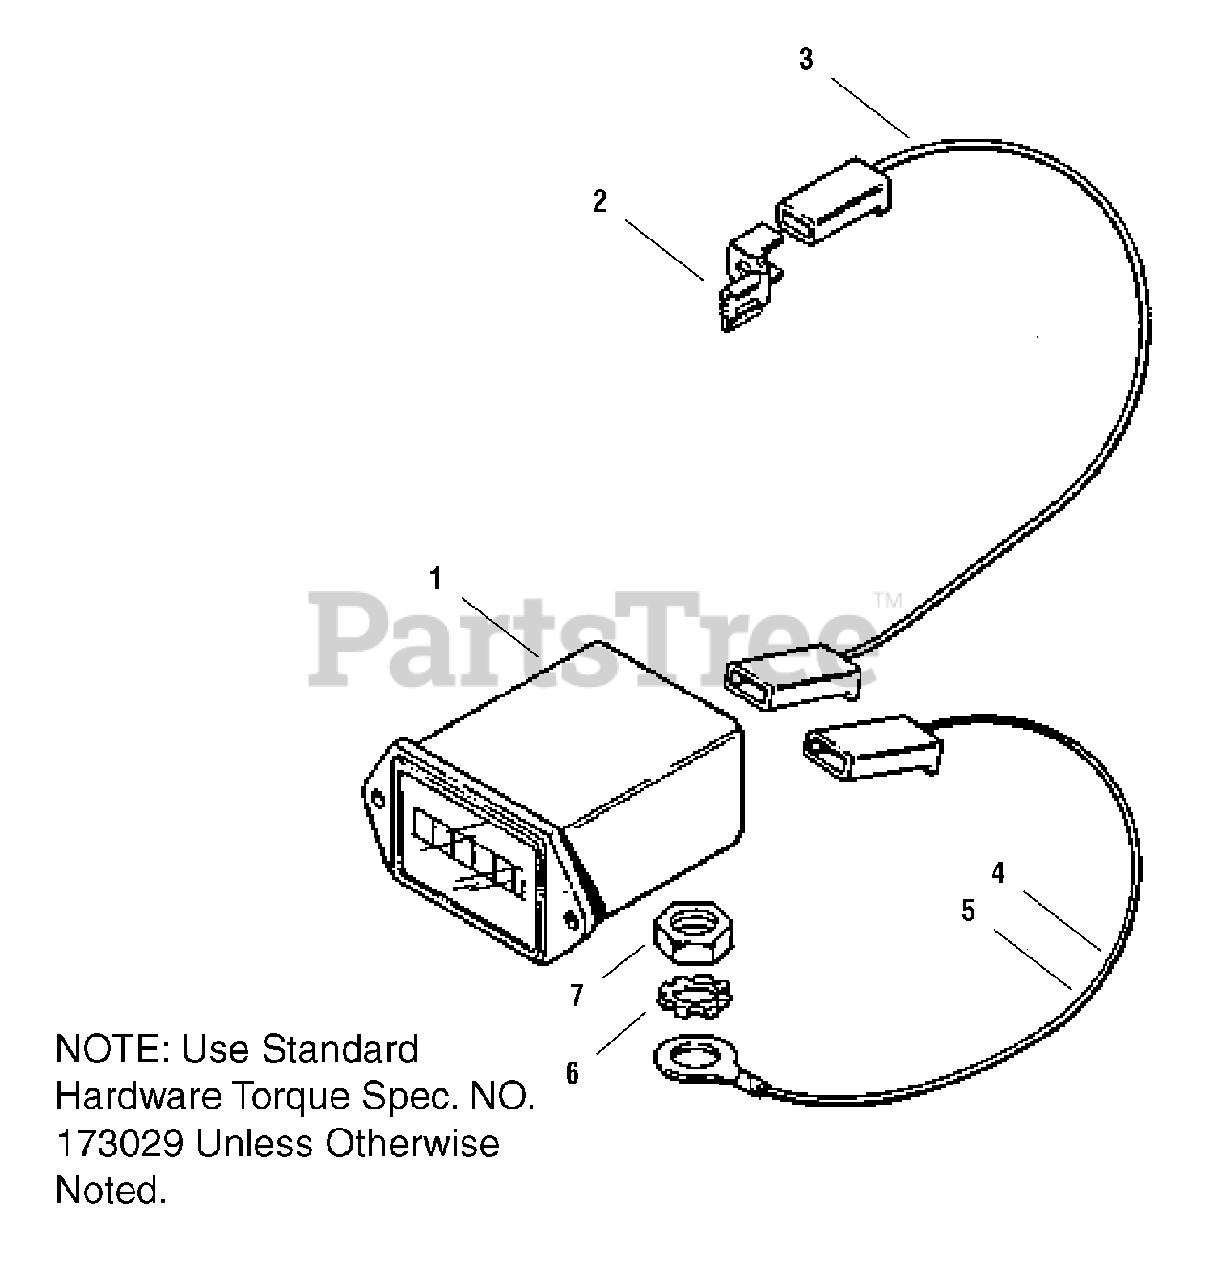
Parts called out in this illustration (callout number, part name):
1	METER, Hour
3	WIRE ASSEMBLY (4000,6000)
4	WIRE, Meter to Ground (7000, 9000)
5	WIRE, Meter To Ground (4000, 6000)
6	LOCKWASHER, External, 1/4
7	NUT, Hexagon, Full, 1/4-20
